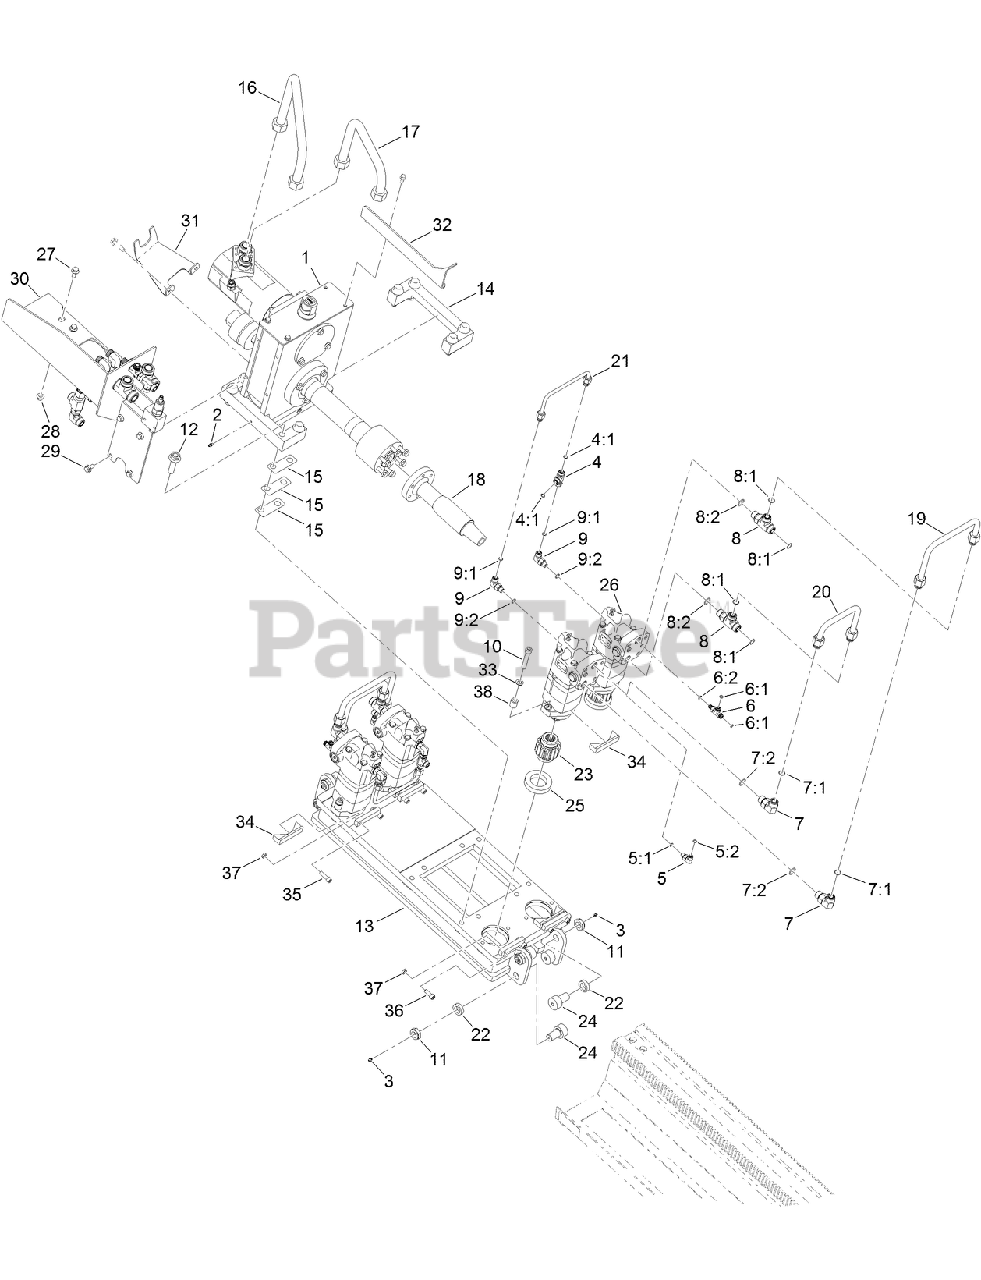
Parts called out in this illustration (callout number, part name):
1	ROTARY GEARBOX ASM
2	FITTING-GREASE
3	FITTING-GREASE, ZERK
4	FITTING-TEE, SWIVEL NUT
4:1	O-RING
5	FITTING-90 DEG
5:1	O-RING
5:2	O-RING
6	FITTING-TEE
6:1	O-RING
6:2	O-RING
7	FITTING-ELBOW-90
7:1	O-RING
7:2	O-RING
8	FITTING-TEE
8:1	O-RING
8:2	O-RING
9	FITTING-ELBOW, 90 DEG
9:1	O-RING
9:2	O-RING
10	SCREW-HSH
11	NUT-LOCK, NI
12	SCREW-HHF
13	CARRIAGE
14	BLOCK-SLIDE, ROTARY
15	SHIM-BLOCK, ROTARY SLIDE
16	TUBE-HYD, HIFLOW (ROTARY B)
17	TUBE-HYD, HIFLOW (ROTARY A)
18	ADAPTER-FLANGE
19	TUBE-HYD, HIFLOW
20	TUBE-HYD, HIFLOW
21	TUBE-HYD, HIFLOW
22	SPACER-FOLLOWER, CAM
23	PINION-INPUT, 15T
24	BEARING-ROLLER, CAM
25	BEARING-BALL, DOUBLE SEALED
26	HYD MOTOR ASM
27	SCREW-HHF
28	NUT-HF
29	SCREW-HHF
30	MOUNT-CARRIER, HOSE
31	BRACKET-SWIVEL, MUD
32	PLATE-FLAG, SENSOR
33	WASHER
34	BRACE-MOTOR, FLOATING
35	SCREW-HSH
36	SCREW-HSH
37	NUT-JAM
38	SPACER
